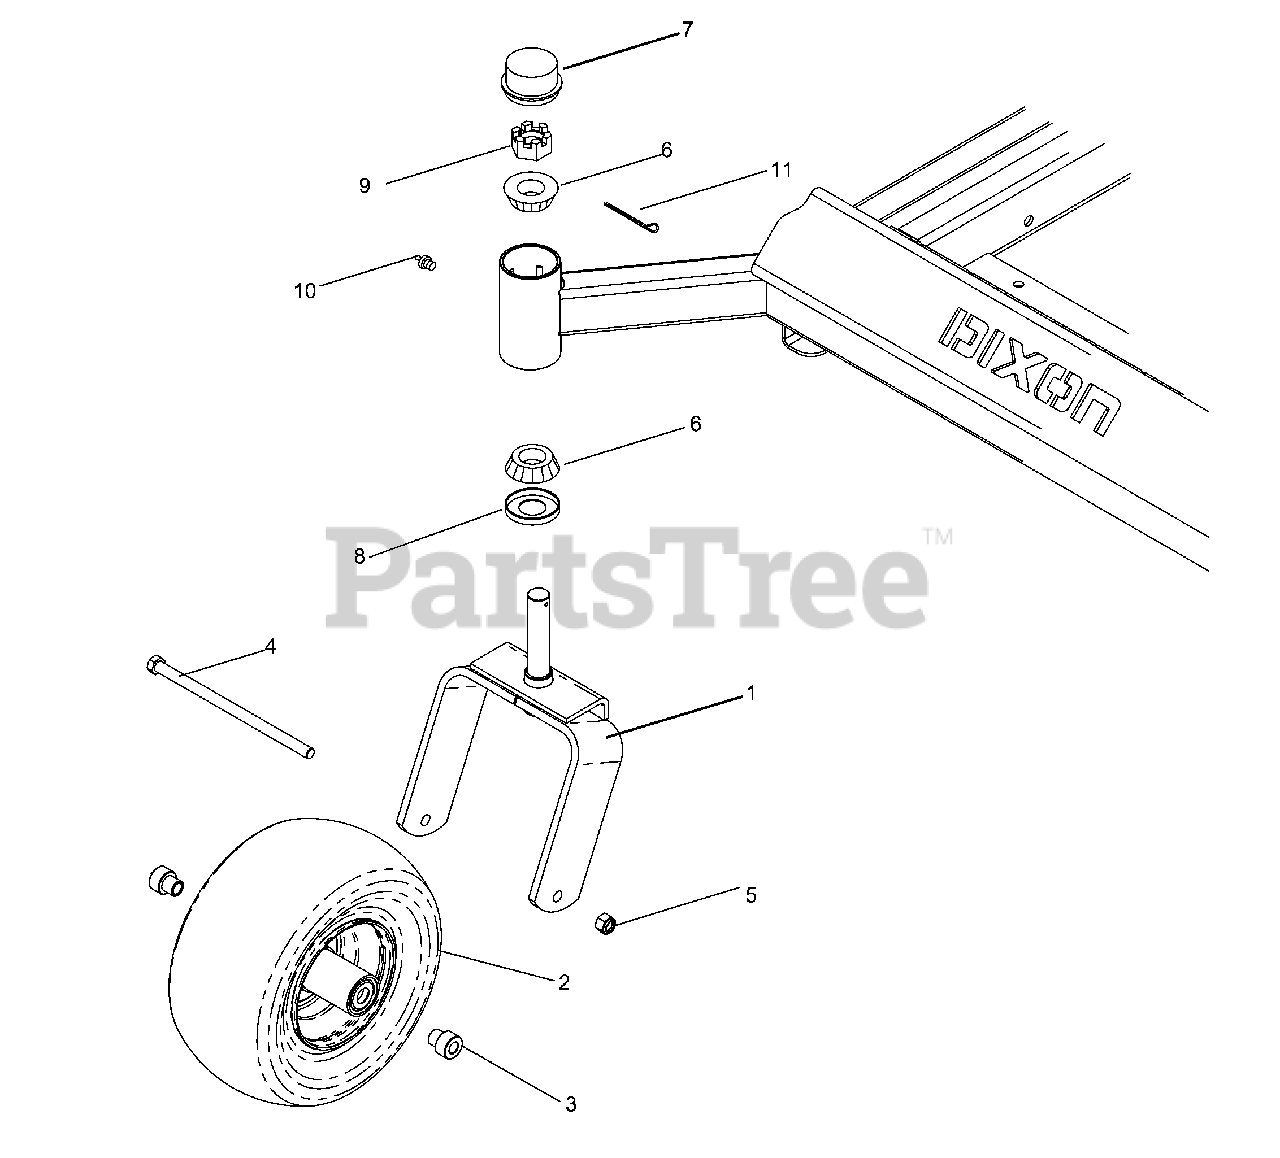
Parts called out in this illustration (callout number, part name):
1	YOKE, CASTER, BLUE
2	FRONT TIRE ASSY
3	AXLE SPACER
4	HEX SCREW 1/2-13 X 9.5 GR5
5	NUT 1/2-13 HEX NYLOC ZD
6	TAPERED ROLLER BRG
7	GREASE CAP
9	NUT 1"C HEX SLOTTED
11	COTTER PIN 1/8 X 2
